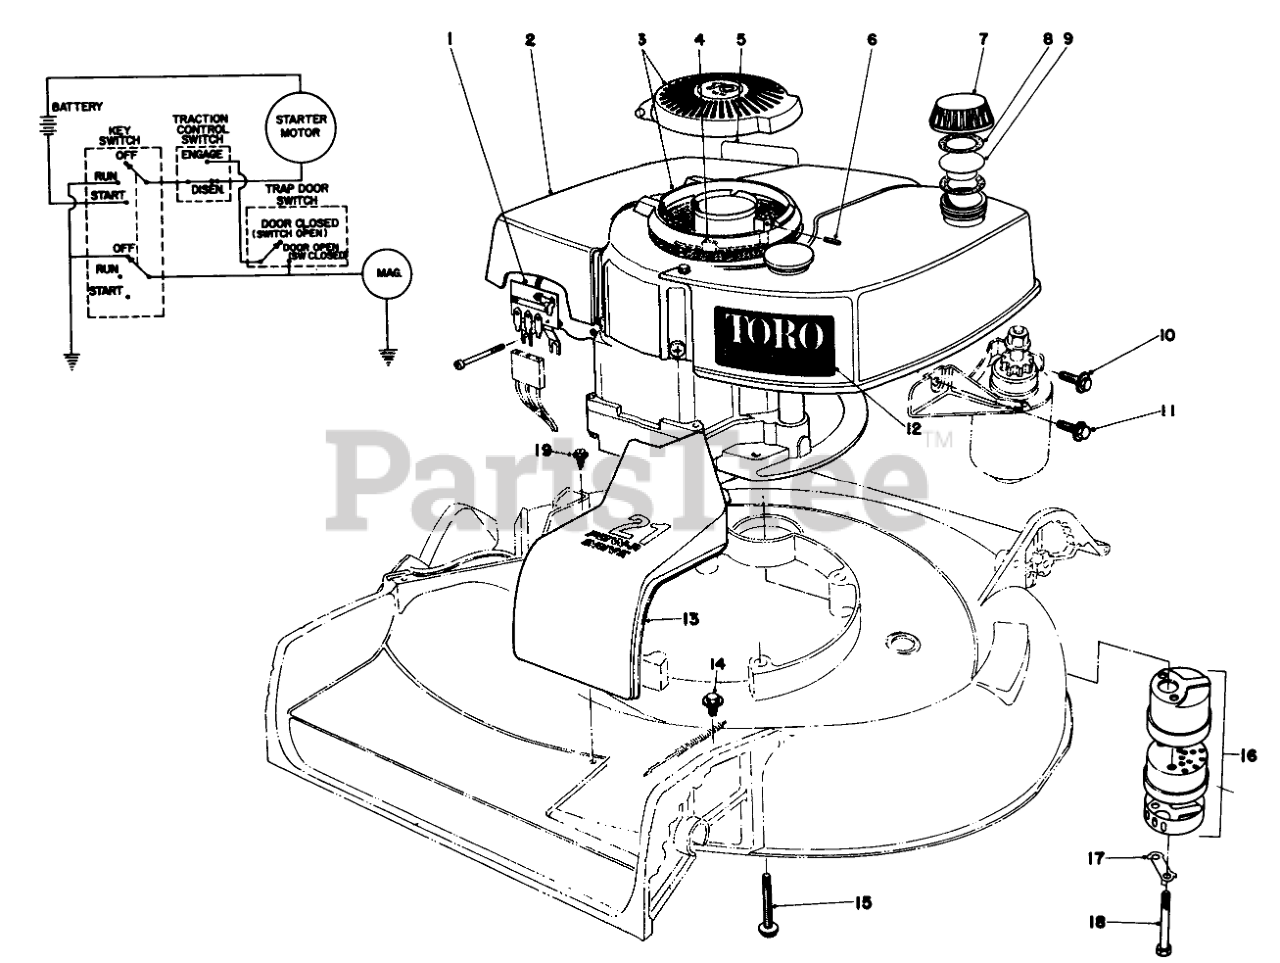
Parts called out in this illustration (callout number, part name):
1	SWITCH & TERM BLK CVR
2	Engine
3	Cover Assembly
4	WIRE CLIP
5	Decal-Maintenan
6	SPRING PIN
7	Gas Cap (Incl. Ref. #8 & 9)
8	GASKET
9	GAS CAP BAFFLE
10	SCREW
11	Screw
12	Decal
13	Cover Belt Drive
14	SCREW-HWHTF
15	3/8-16 X 2-3/4 CAPSCR
16	MUFFLER ASM
17	CLIP - LOCKING
18	SCREW-HH
19	SCREW
